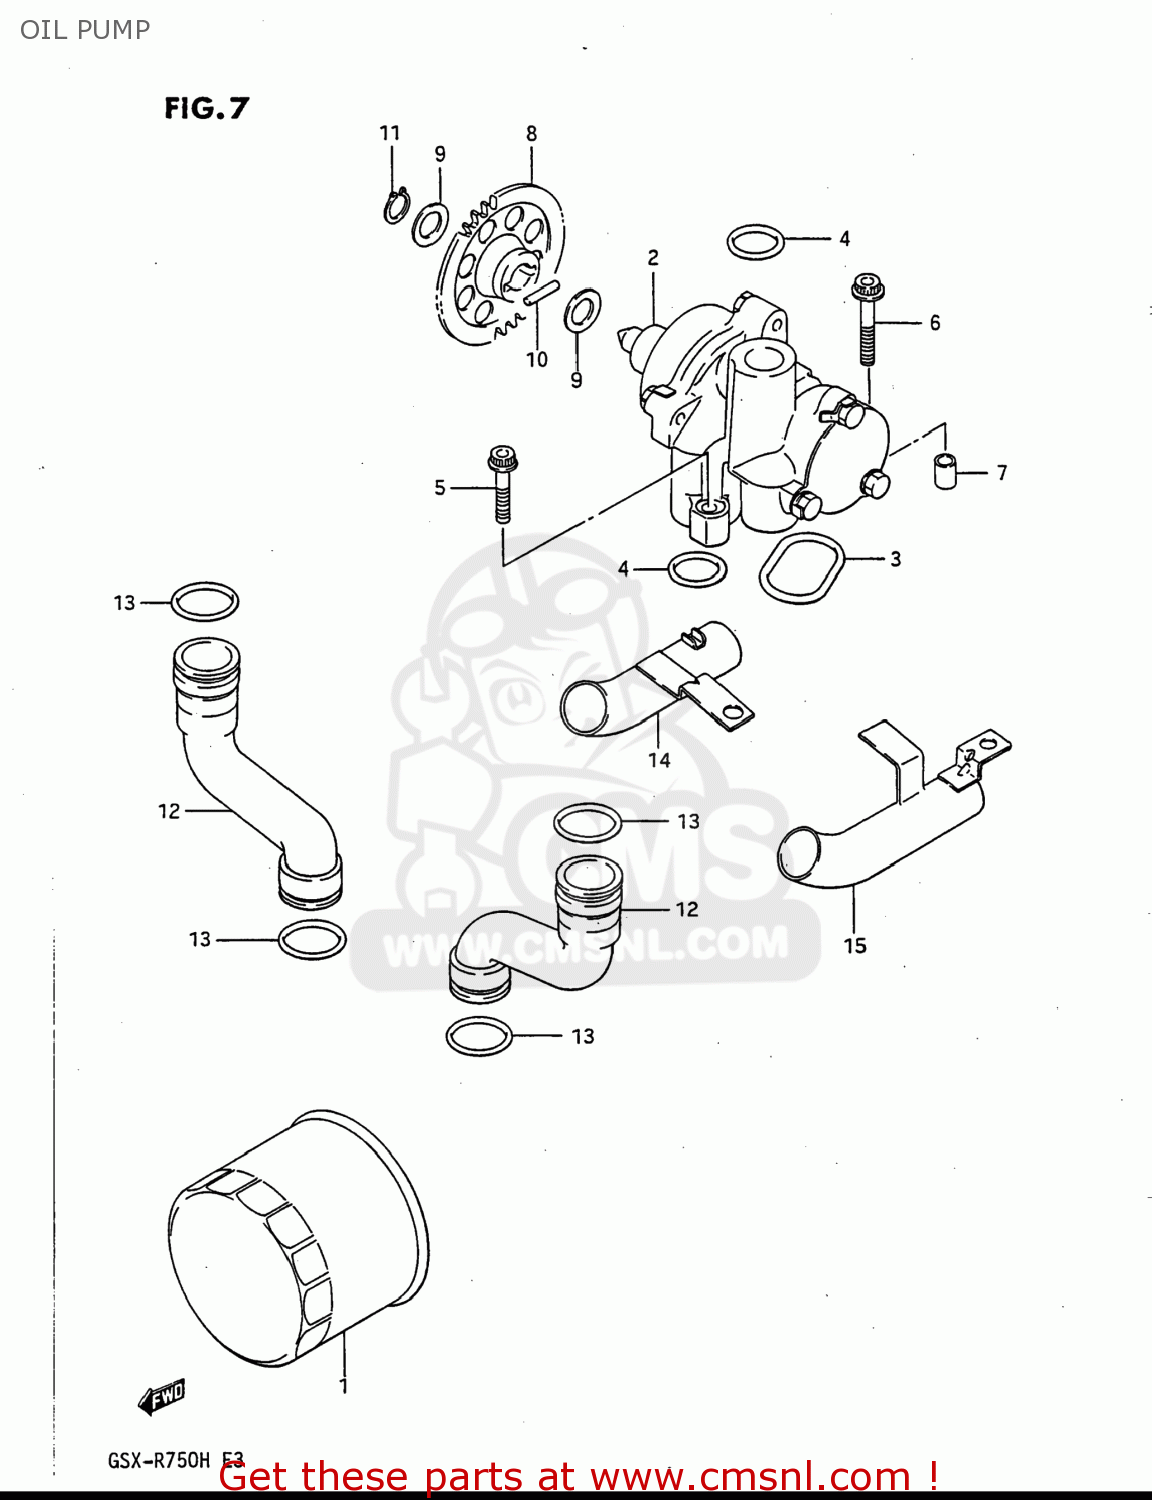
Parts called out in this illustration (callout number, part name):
1	FILTER ASSY,ENGINE OIL
2	PUMP ASSEMBLY,OIL
3	O RING,OIL PUMP
4	O RING(D:3.2,ID:17.8)
5	BOLT
6	BOLT
7	PIN
8	GEAR,OIL PUMP DRIVEN
9	SHIM
10	PIN(5X18)
11	CIRCLIP
12	HOSE,OIL
13	O-RING
14	PIPE,OIL,OUTLET,UNDER
15	PIPE,OIL,OUTLET,UNDER
